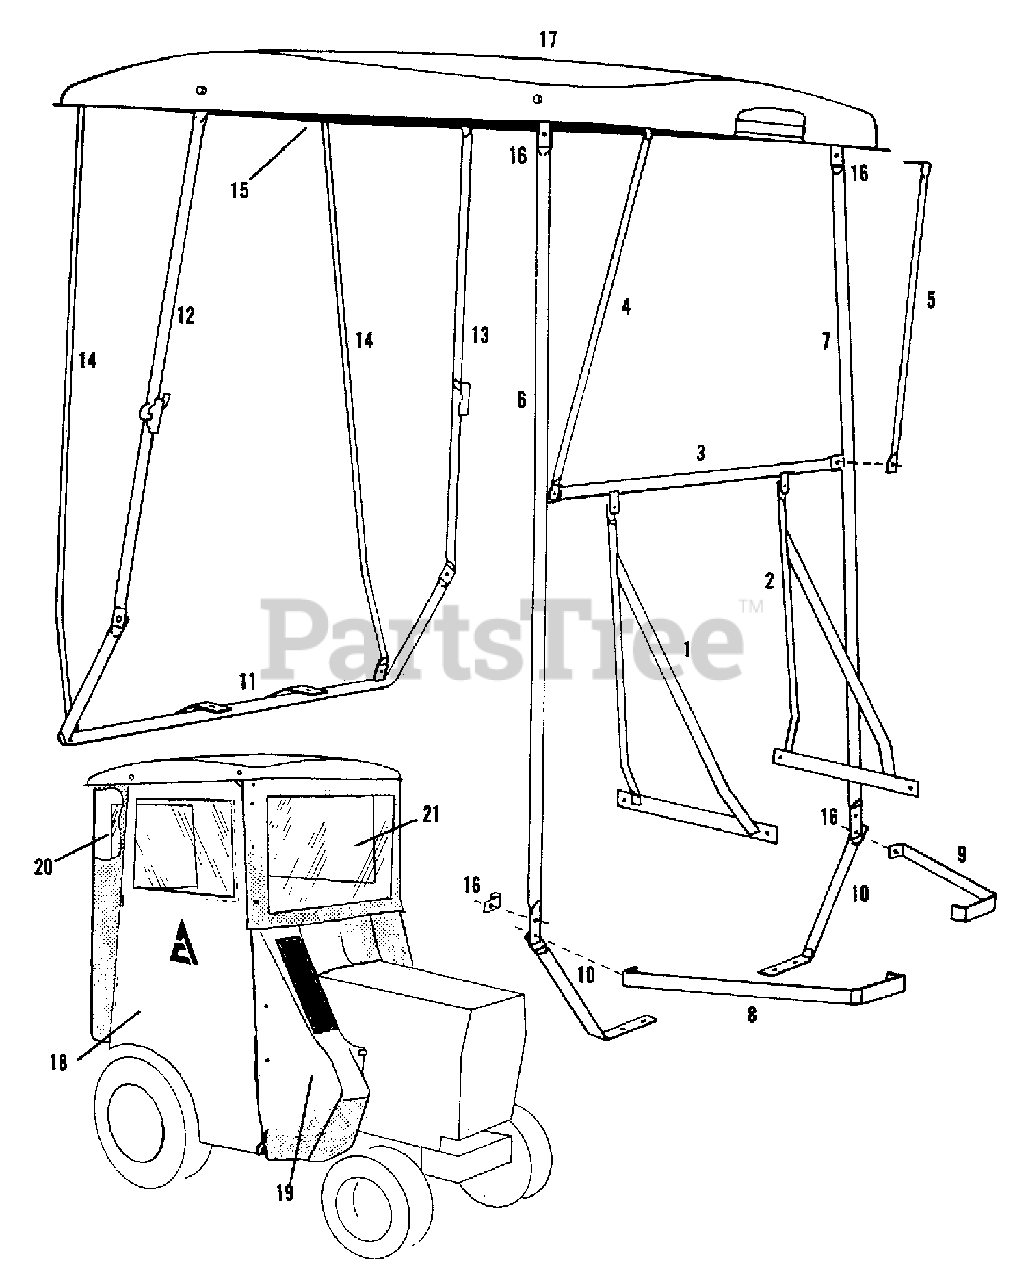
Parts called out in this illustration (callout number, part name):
1	BRACKET, Front Attaching, R.H.
2	BRACKET, Front Attaching, L.H.
3	BAR, Front Cross
3	CAPSCREW, 1/4NC x 3/4
3	NUT, 1/4NC, Lock
4	BRACE, Top, R.H.
5	BRACE, Top, L.H.
5	CAPSCREW, 1/4NC x 1-1/4
5	NUT, 1/4NC, Lock
6	POST, Front Corner, R.H.
7	POST, Front Corner, L.H.
8	BRACE, Foot Pocket, R.H.
9	BRACE, Foot Pocket, L.H.
9	CAPSCREW, 1/4NC x 3/4
9	NUT, 1/4NC, Lock
10	FOOT, R.H. & L.H.
10	CAPSCREW, 1/4NC x 3/4
10	NUT, 1/4NC, Lock
11	BRACKET, Rear Attaching
12	POST, Rear Corner, R.H.
13	POST, Rear Corner, L.H.
13	CAPSCREW, 1/4NC x 3/4
13	NUT, 1/4NC, Lock
14	POST, Rear Curtain R.H. & L.H.
14	CAPSCREW, 1/4NC x 3/4
14	NUT, 1/4NC, Lock
15	CAPSCREW, 1/4NC x 3/4
15	NUT, 1/4NC, Lock
16	HINGE, Door
16	CAPSCREW, 1/4NC x 3/4
16	NUT, 1/4NC, Lock
17	TOP, Fiber Glass
17	CAPSCREW, 1/4NC x 3/4
17	WASHER, 1/4, Lock
17	NUT, 1/4NC, Lock
18	DOOR, R.H.
18	DOOR, L.H.
19	PANEL, Front Vinyl
20	CURTAIN, Rear Vinyl
21	WINDSHEILD, Plastic
